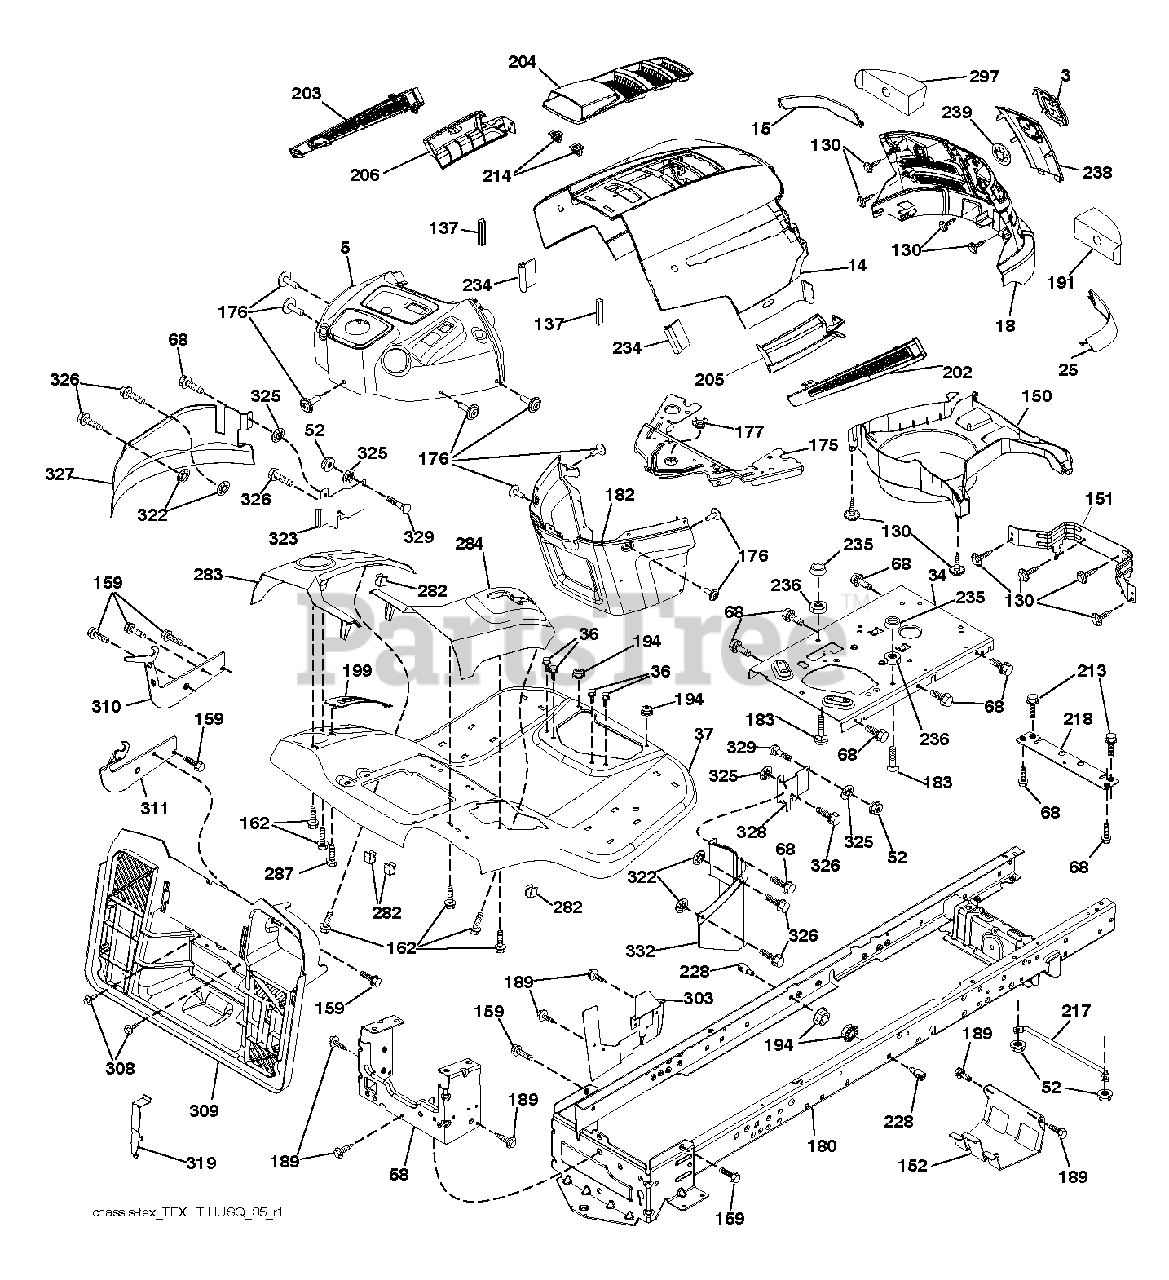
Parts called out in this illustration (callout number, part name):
3	RP LOGO
14	HOOD
15	LENS RH
18	GRILLE.SVC.HUSQVARNA.LT.GREY
25	LENS LH
34	PLATE.ENGINE.WELDED.CHASSIS
36	SCREW 5/16"
37	FENDER.TEX.SRD.CRD.FRN.GUARDS
52	LOCKNUT
58	DRAWBAR UPPER 2PC SMALL FENDER
68	SCREW LT
130	SCREW.#10 X 0.750.BOS
137	BUMPER DASH
151	BRACKET PIVOT
152	SHIELD.BROWNING.W/TEX
159	SCREW, 3/8-16X3/4
162	SCREW.HI-LO.CONSOLE
175	CROSSMEMBER
176	SCREW.#10-24X5/8.RN.QU
177	BUSHING STEERING
180	CHASSIS.WLDMNT.14GA.2PC.18".TI
182	DASH.LOWER.PREDATOR LT
183	BOLT.5/16-18X1-1/4 FULL THD
189	SCREW
191	INSERT.REFLECTIVE.RH.
194	NUT LOCK HEX FLANGE 5/16-18
199	PLATE DECK LIFT
202	VENT SIDE HOOD LH
203	VENT SIDE HOOD RH
204	VENT TOP HOOD
205	SKIRT SIDE RH
206	SKIRT SIDE LH
213	BOLT
214	CLIP.RETAINER.TINNER.
217	ROD.PIVOT.HOOD
218	X-PIECE.HOOD.STOP.NON/
228	STUD.FASTNER.W/ANTI-ROTATE
234	BUMPER.HOOD.TEX.HUSQVARNA
235	SPACER FENDER
236	NUT.CENTERLOCK.5/16-
238	TRIM
282	CLIP.RETAINER.CONSOLE.LT.HUSQ
283	CONSL.DECKLIFT.LH.SRD.TEX.CRD
284	CONSL.SHFT.PEDAL.RH.SRD.TEXCRD
287	SCREW 1/4X20
297	INSERT REFLECTIVE
303	SHIELD CHASSIS LEFT
308	BOLT, 5/16-18 X 1 3/4
309	BACKPLATE.BAGGER.V2.SRD
319	BRACKET.ACTUATOR.BAGGER.SRD
322	PALNUT 1/4
323	GUARD FRONT LEFT
325	WASHER 5/16"
326	SCREW 14-20 X 5/8
327	GUARD LEFT
328	GUARD FRONT RIGHT
329	BOLT
332	GUARD RIGHT
